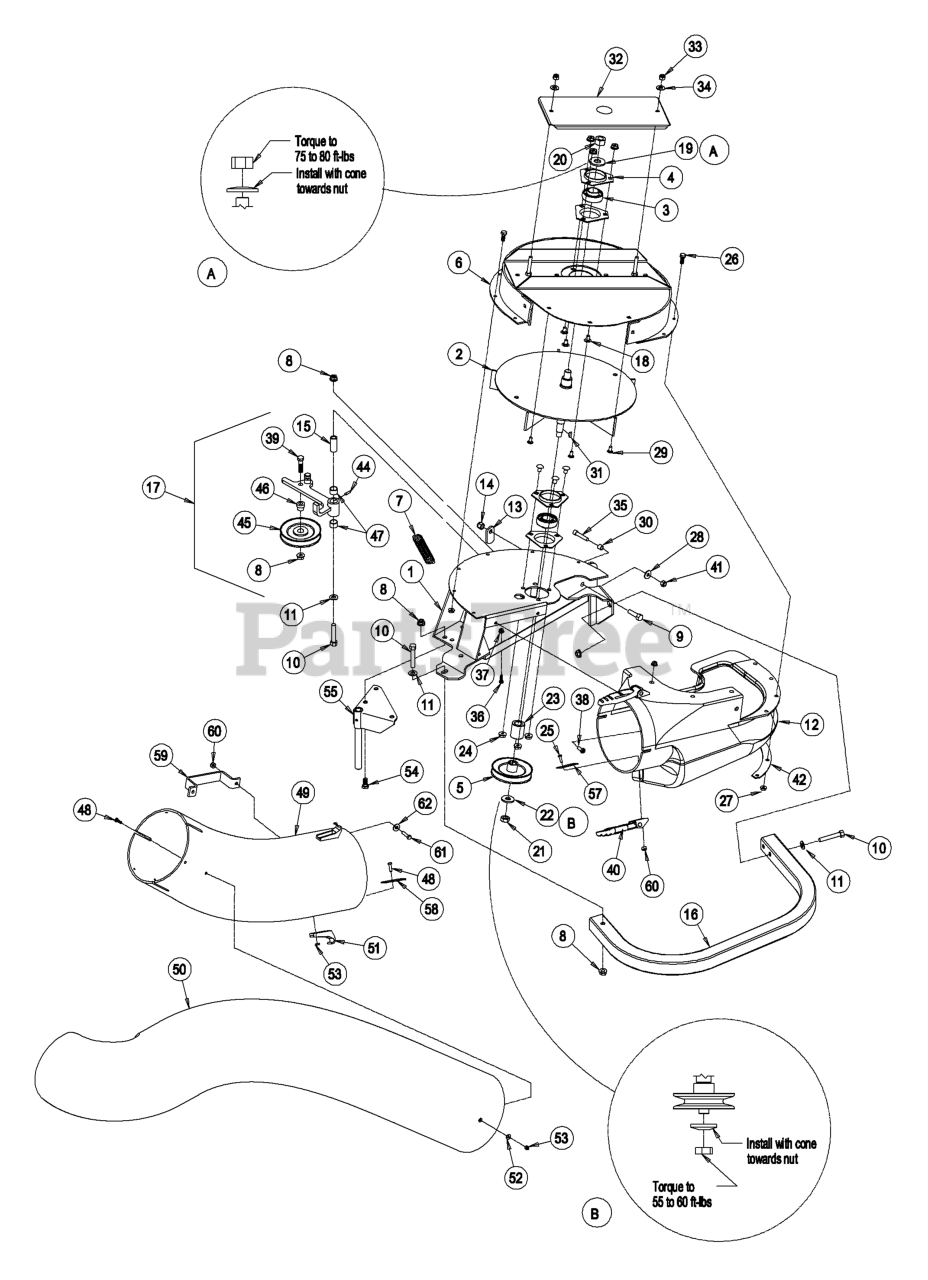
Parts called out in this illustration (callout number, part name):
2	IMPELLER
3	BEARING
4	HOUSING-FLANGE
5	SHEAVE
6	ASM, UPPER HSG
7	SPRING-IDLER
8	NUT-HHF, WHIZ
9	SCREW-HH
10	SCREW-HH
11	WASHER-FLAT
13	LATCH-CATCHER, GRASS
14	NUT-LOCK, NI
15	BUSHING
17	ASM, IDLER ARM - SERVICE
18	SCREW-CARR
19	WASHER-SPRING
20	NUT-HEX
21	NUT-JAM
22	WASHER-SPRING
25	SCREW-HH
26	SCREW-HH
28	WASHER-SPRING
29	SCREW-CARR
30	BUSHING, LOCATOR
31	KEY-WOODRUFF
32	ASM, BEARING COVER
33	NUT-LOCK, NI
34	WASHER-FLAT
35	SCREW-HSH
36	SCREW-HEAD, TRUSS
39	SCREW-HH
40	LATCH-RUBBER
41	NUT-HEX
42	PLATE-BACKING, BLOWER
44	FITTING-GREASE
46	HUB,SPACER
47	BUSHING
48	SCREW-HWH
51	LATCH-CATCH
52	WASHER-FLAT
53	NUT-LOCK, NI
54	SCREW-HH
55	PIN-MOUNT
56	ASM, BLOWER LZ60/72 - SER
57	PLATE-BACKING
58	PLATE-BACKING
60	NUT-LOCK, NI
61	SCREW-HH
62	WASHER-FLAT
